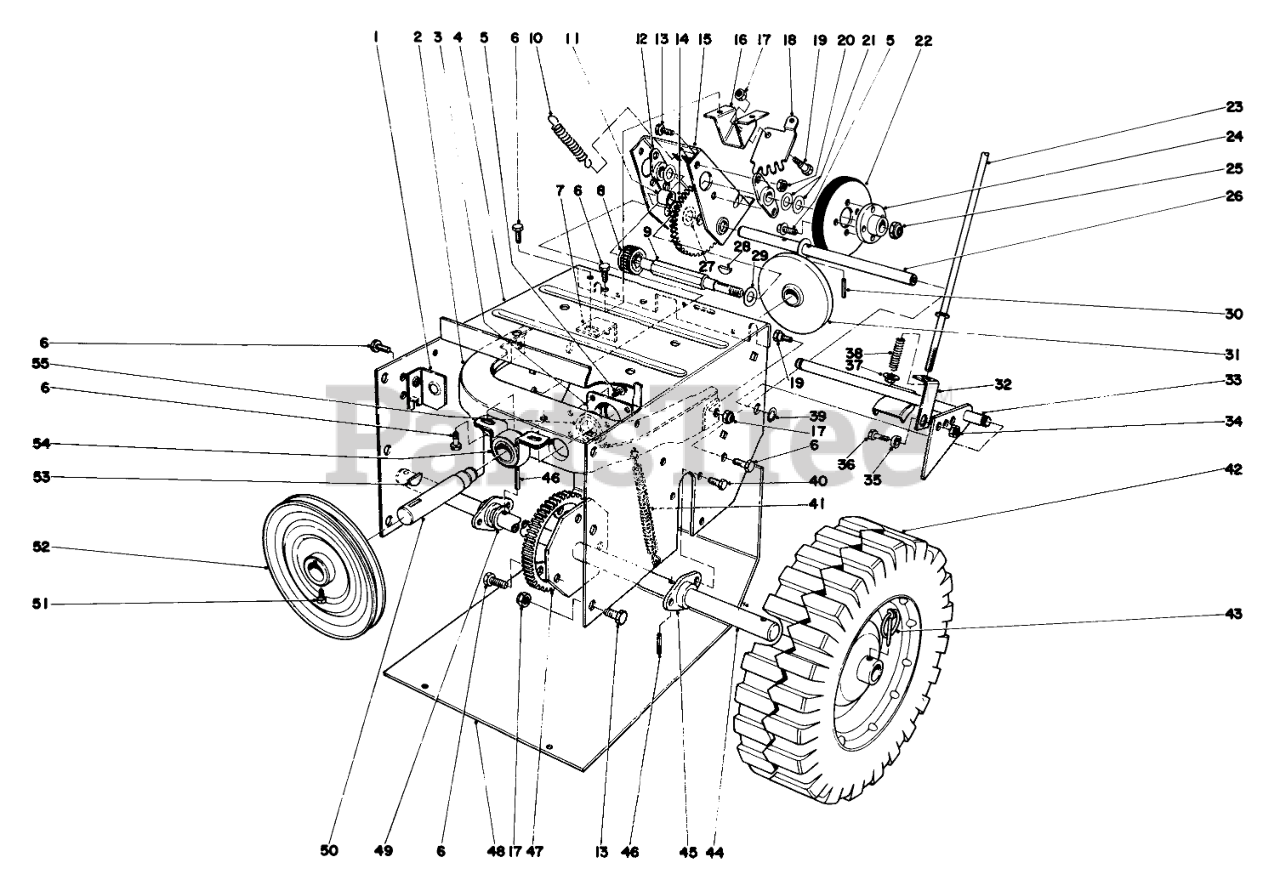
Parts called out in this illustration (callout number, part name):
1	AUGER CLUTCH MTG FRT
2	"OBS" FRICTION PLT FRAME
3	CUP-BEARING
4	Frame-Traction
5	SCREW
6	SCREW-HWHTF
7	BRACKET-MOUNT, REAR
8	PINION
9	SHAFT-WHEEL, FRICTION
10	SPRING-TRACTION
11	5/8ID X 1LG BUSHING
12	BEARING-WHEEL, FRICTION
13	SCREW-HH
14	Intermediate Gear (Incl. Ref. #11)
15	Bracket Sliding
16	MOUNT-LEVER
17	NUT-LOCK, NI
18	GEAR-QUADRANT
19	BOLT-SHOULDER
20	NUT-LOCK, CONE
21	WASHER-THRUST
22	WHEEL-FRICTION
23	Lower Traction Rod
24	Hub-Friction Wheel Mounting
25	NUT-LOCK, NI
26	SHAFT-PIVOT
27	WASHER-SPECIAL
28	KEY-WOODRUFF
29	WASHER-FLAT
30	PIN-SPRING
31	PLATE-FRICTION
32	BRACKET-TRACTION
33	Traction Engagement Arm
34	NUT-LOCK, CONE
35	Spacer-Traction Bracket
36	SCREW-HH
37	NUT-LOCK, HHF
38	SPRING
39	RING-RETAINING
40	Screw
41	SPRING-PLATE, FRICTION
42	Wheel
43	PIN-LYNCH
44	AXLE SHAFT WA
45	BEARING-AXLE
46	PIN-SPRING
47	GEAR-AXLE
48	Bottom Cover
49	WASHER-THRUST
50	Shaft Friction Plate
51	SCREW-SET, SQH
52	Pulley
53	KEY-WOODRUFF
54	BUSHING ASM
55	Bearing
